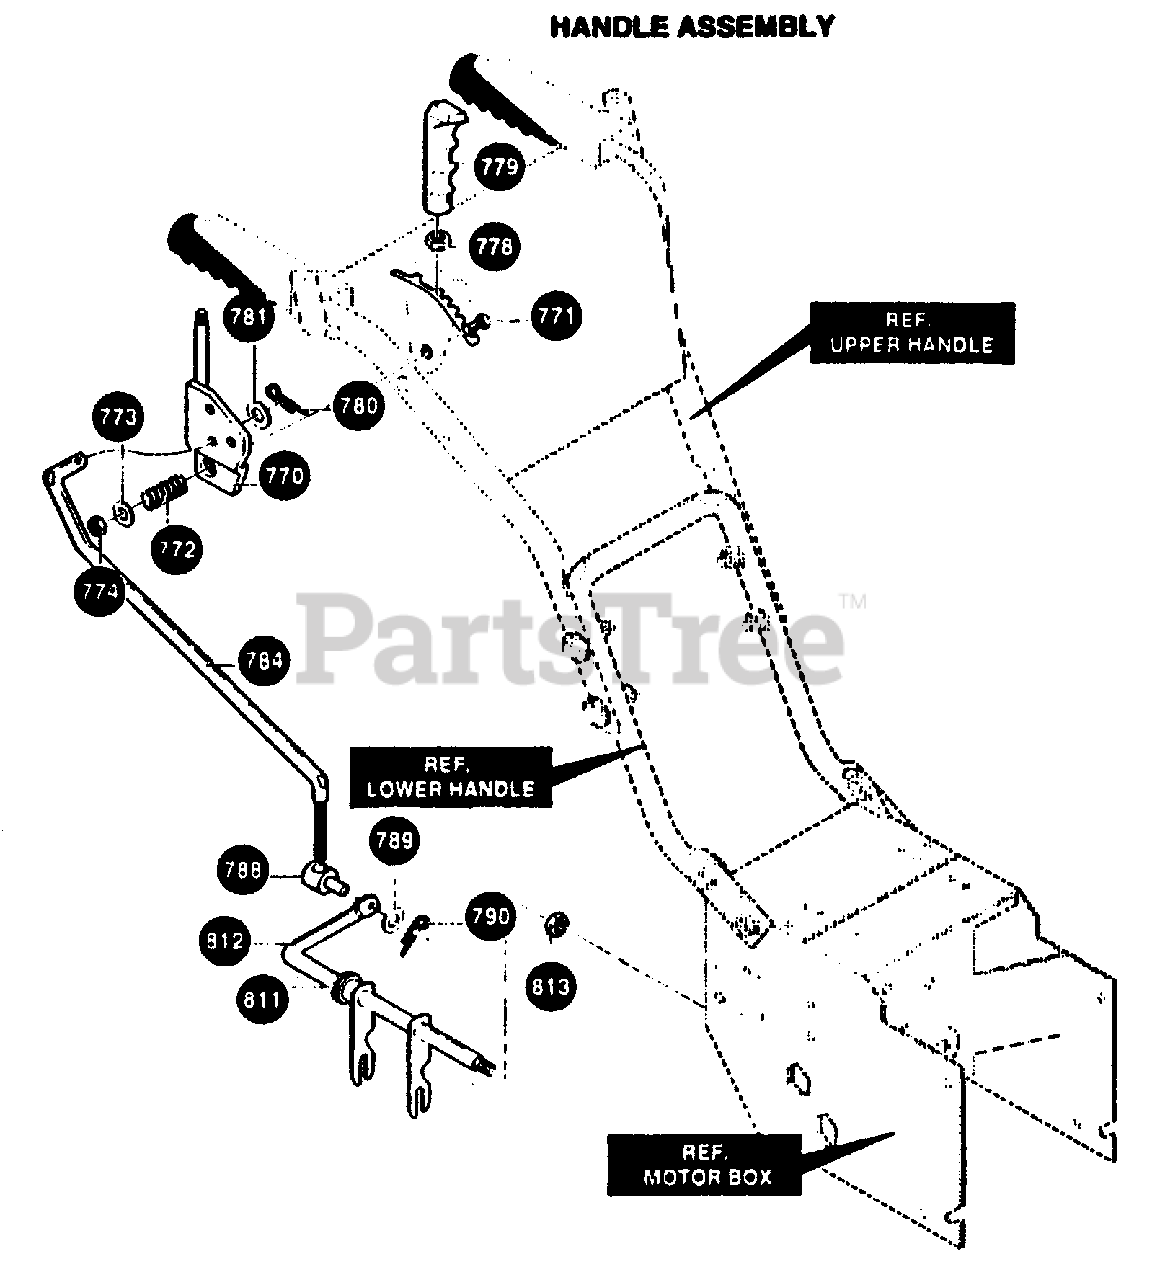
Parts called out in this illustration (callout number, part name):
770	HANDLE ASSY SPD CTRL
771	SCREW 3/8-16X2.00
773	FLATWASHER .406 X .81X.065
774	NUT, 3/8-16 HEXNYL
778	NUT, 3/8-16 RGHXCTRLK
779	HANDLE 3/8-16
780	PIN, COTTER
781	FLATWASHER
784	ROD, SPEED CONTROL
788	NUT, TRUNNION
789	FLATWASHER
790	COTTER PIN
811	BEARING, FLANGE
812	ROD, ASSY YOKE
813	NUT, 3/8-16 RGHXCTRLK
